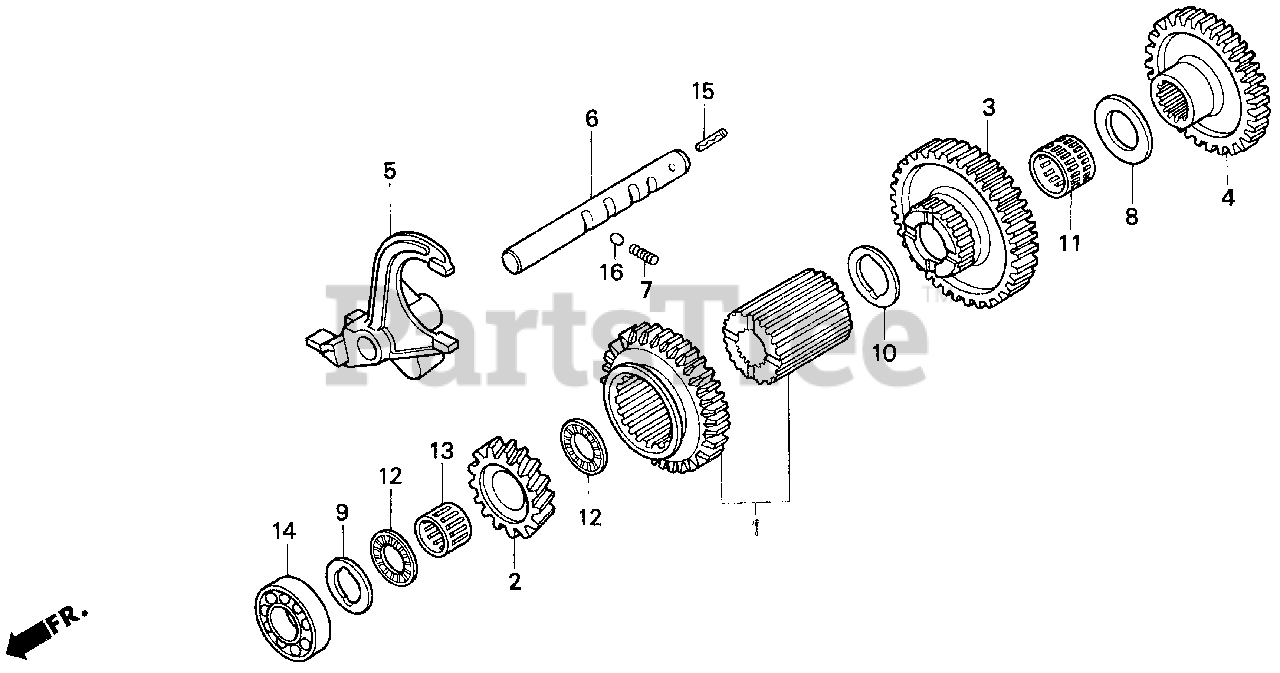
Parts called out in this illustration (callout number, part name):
1	CHANGE SET, AUXILIARY
2	GEAR, AUXILIARY DRIVEN HIGH (16T)
3	GEAR, L. AUXILIARY DRIVEN (48T)
4	GEAR, FR. DRIVE (29T)
5	FORK, AUXILIARY SHIFT
6	SHAFT, AUXILIARY SHIFT FORK
7	SPRING, BALL SETTING
8	WASHER, THRUST (25X40X2)
9	SHIM A, FINAL SHAFT (1.5MM)
9	SHIM B, FINAL SHAFT (2.0MM)
9	SHIM C, FINAL SHAFT (2.5MM)
10	WASHER, THRUST (25X35X2)
11	BEARING, NEEDLE (25X29X22) (TOYO)
12	NEEDLE, THRUST (20X35X2.8)
13	BEARING, NEEDLE (20X24X17)
14	BEARING, RADIAL BALL (6204) (TOYO)
15	PIN, SPRING (3X18)
16	BALL, STEEL (#10) (5/16)
